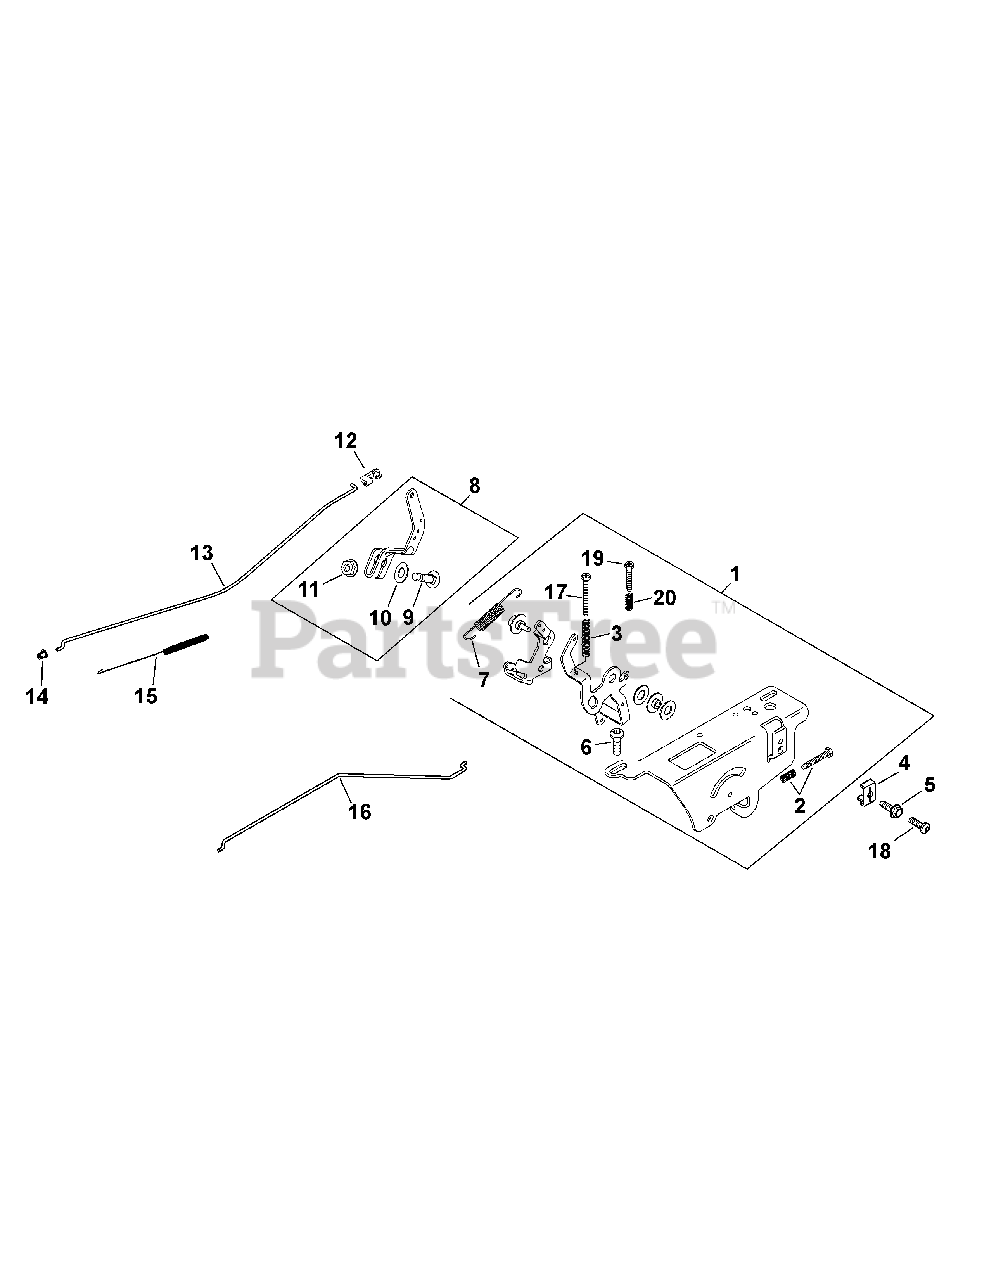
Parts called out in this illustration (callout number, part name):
1	Speed Control Assembly Kit
2	Idle Adj. Screw & Spring Kit
3	Fuse Block
4	Cable Clamp
5	Flg. Thd. Frm. Screw, M5 X 0.8 X 16
6	Lbd. Skt. Screw, M6 X 1.0 X 20
7	Governor Spring
8	Governor Assembly Lever (Inc. 9-11)
9	Rd. Hd. Sq. Nck. Bolt, 1/4-20 X 1
10	Int. Tooth Lock Washer, 1.4
11	Hex Flange Nut, 1.4-20
12	Throttle Linkage Bushing
13	Throttle Linkage
14	Linkage Retaining Bushing
15	Linkage Spring
16	Choke Linkage
17	Fuse Block
18	Fuse Block
19	Phl. Thd. Frm. Screw, M4 X 0.7 X 25
20	Speed Control Spring (Short)
